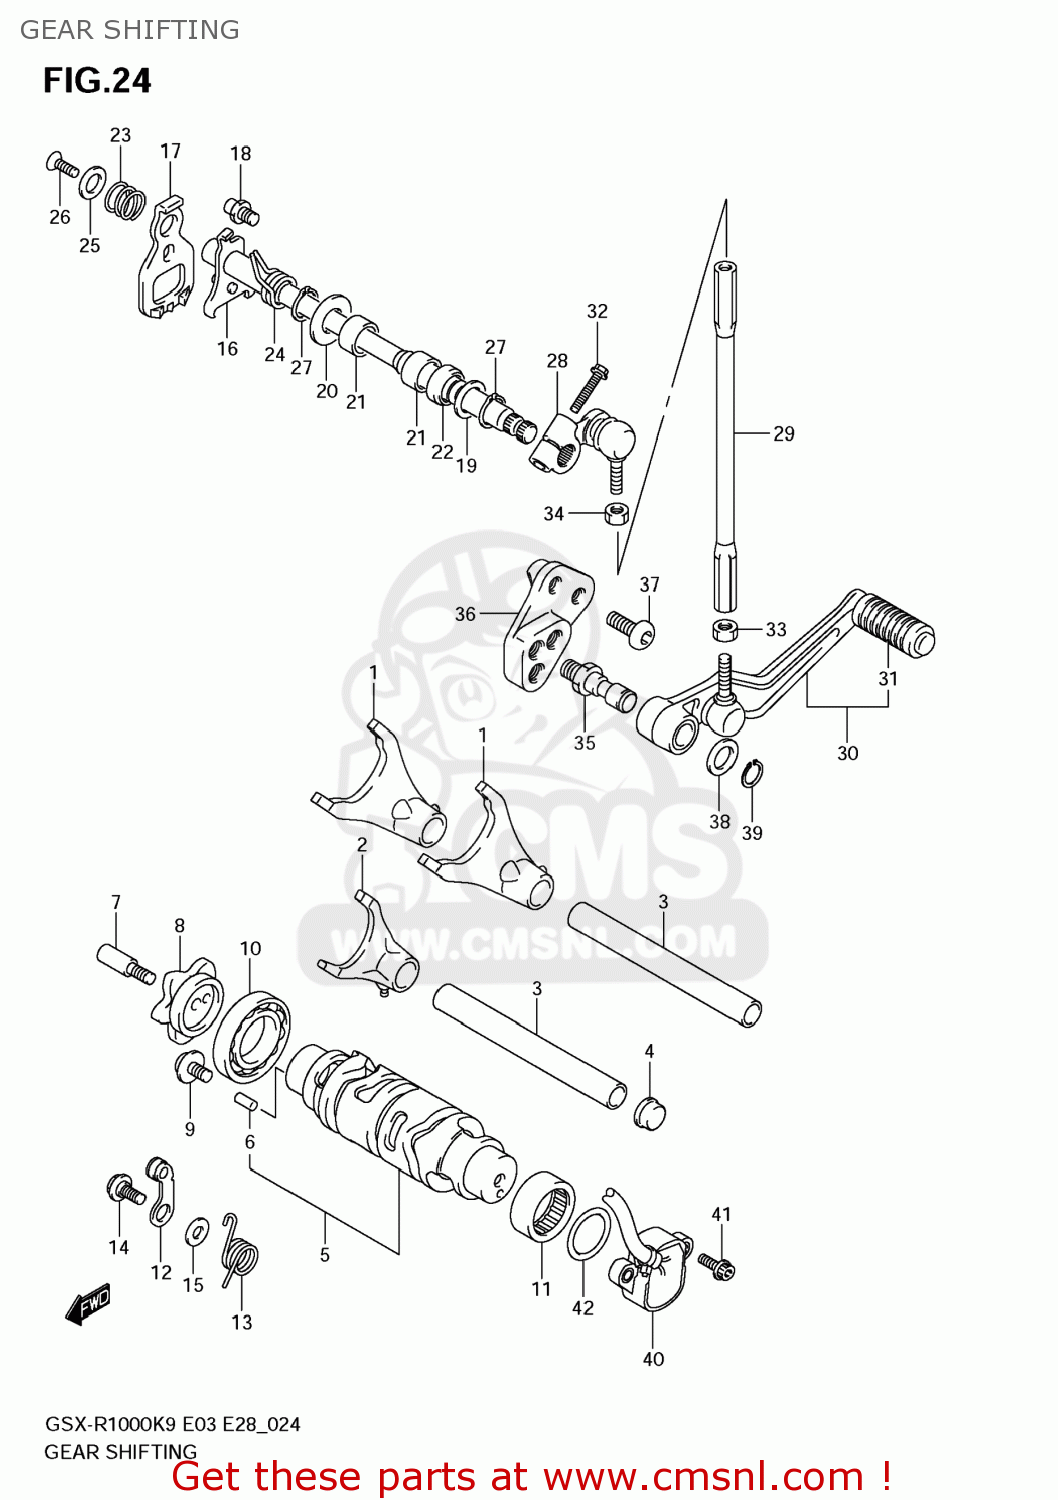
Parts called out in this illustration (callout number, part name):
1	FORK,GEAR SHIFT NO.1
2	FORK,GEAR SHIFT NO.3
3	SHAFT,GEAR SHIFT FORK(L:128)
4	PLUG,GEAR SHIFT FORK SHAFT
5	CAM,GEAR SHIFT
6	PIN
7	BOLT,GEAR SHIFT CAM PLATE
8	PLATE,GEAR SHIFT CAM
9	SCREW(6X12)
10	BEARING(25X47X8)
11	BEARING(25X32X12)
12	STOPPER,SHIFT CAM
13	SPRING,GEAR SHIFT CAM STOPPER
14	BOLT(6X14.3)
15	WASHER
16	SHAFT,GEAR SHIFT
17	PLATE,GEAR SHIFT CAM DRIVE
18	STOPPER,GEAR SHIFT ARM
19	WASHER(14X29X0.8)
20	SHIM(14X24X1)
21	BEARING(14X20X12)
22	SEAL,OIL(14X22X6)
23	SPRING,GEAR SHIFT PLATE RETURN
24	SPRING
25	WASHER,GEAR SHIFT SHAFT END
26	SCREW(6X16)
27	CIRCLIP
28	ARM,GEAR SHIFT LINK
29	ROD,GEAR SHIFT LINK
30	LEVER ASSY,GEAR SHIFT
31	RUBBER,GEAR SHIFT PEDAL
32	BOLT
33	NUT
34	NUT
35	SHAFT,GEAR SHIFT LEVER
36	BRACKET,GEAR S
37	BOLT(8X20)
38	WASHER(12.5X20X1)
39	CIRCLIP
40	SENSOR ASSY,GE
41	BOLT(5X16)
42	O RING(D:2.4,ID:26.2)
